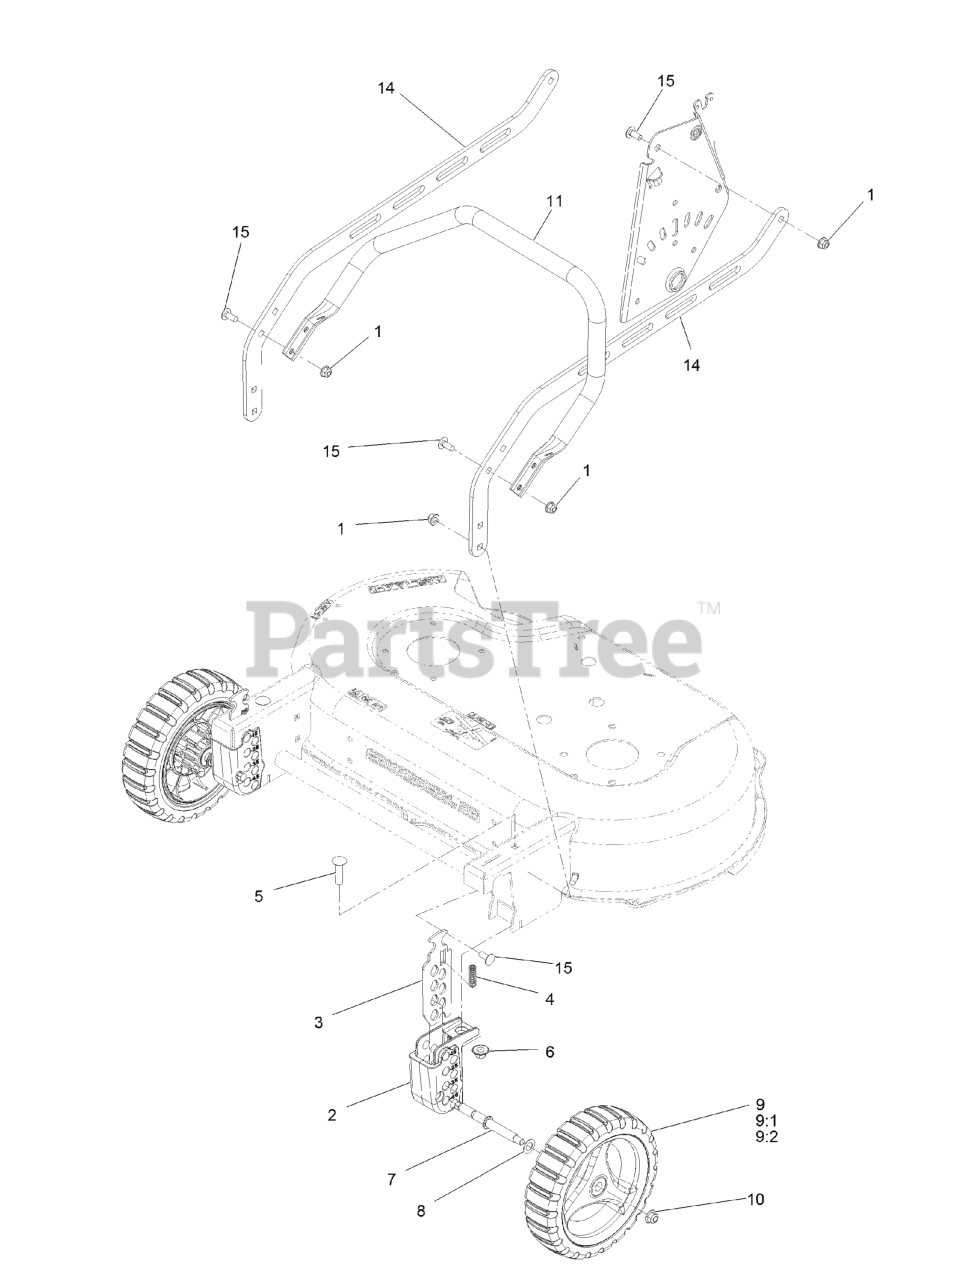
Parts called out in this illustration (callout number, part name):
1	NUT-HF, NI
2	BLOCK-FRONT QUADRANT
3	PLATE, FRONT HEIGHT
4	SPRING-COMPRESSION
5	SCREW-CARR
6	Nut-Nyloc 3/8-16 Flg
7	AXLE-WHEEL
8	WASHER-PLAIN
9	WHEEL ASM, 9" W/BEARINGS
9:1	WHEEL ASM, 9"
9:2	BEARING-BALL
10	NUT-HF, NI
11	GUARD-ENGINE
15	SCREW-CARR
